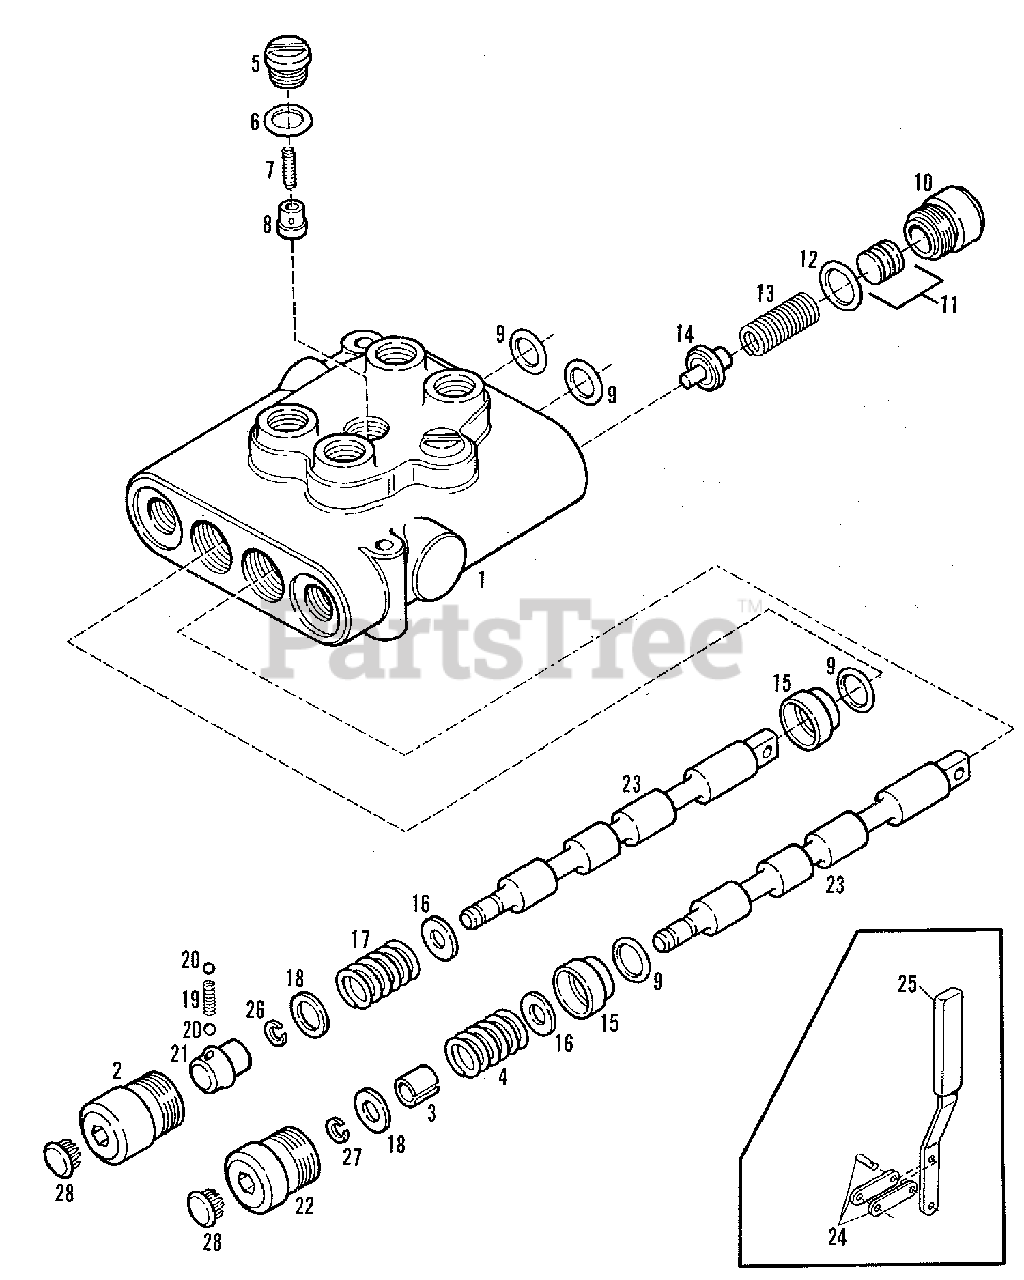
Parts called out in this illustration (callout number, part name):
1	BODY, Valve
3	SPACER, Spool
4	SPRING, Spool Centering
5	PLUG, Lift Check
6	O-RING, Plug Assembly
7	SPRING, Lift Check Plug
8	PLUNGER, Lift Check Plug
9	O-RING, Spool
10	PLUG ASSEMBLY, Relief Valve
11	SHIM, Relief Valve
12	O-RING, Relief Valve Plug
13	SPRING, Relief Valve
14	POPPET, Relief Valve
15	BUSHING, Spool
16	WASHER, Spool
17	SPRING, Spool Centering
18	WASHER, Spool
19	SPRING, Detent
20	BALL, Detent Spring, 5/32" Diameter
21	CAP, Detent Adapter
22	CAP, Detent
23	SPOOL
24	LINK ASSEMBLY, Valve
25	HANDLE ASSEMBLY, Valve
25	PIN, Cotter, 3/16 x 2
26	RING, Retainer
27	RING, Retainer
28	BUTTON, Insert
